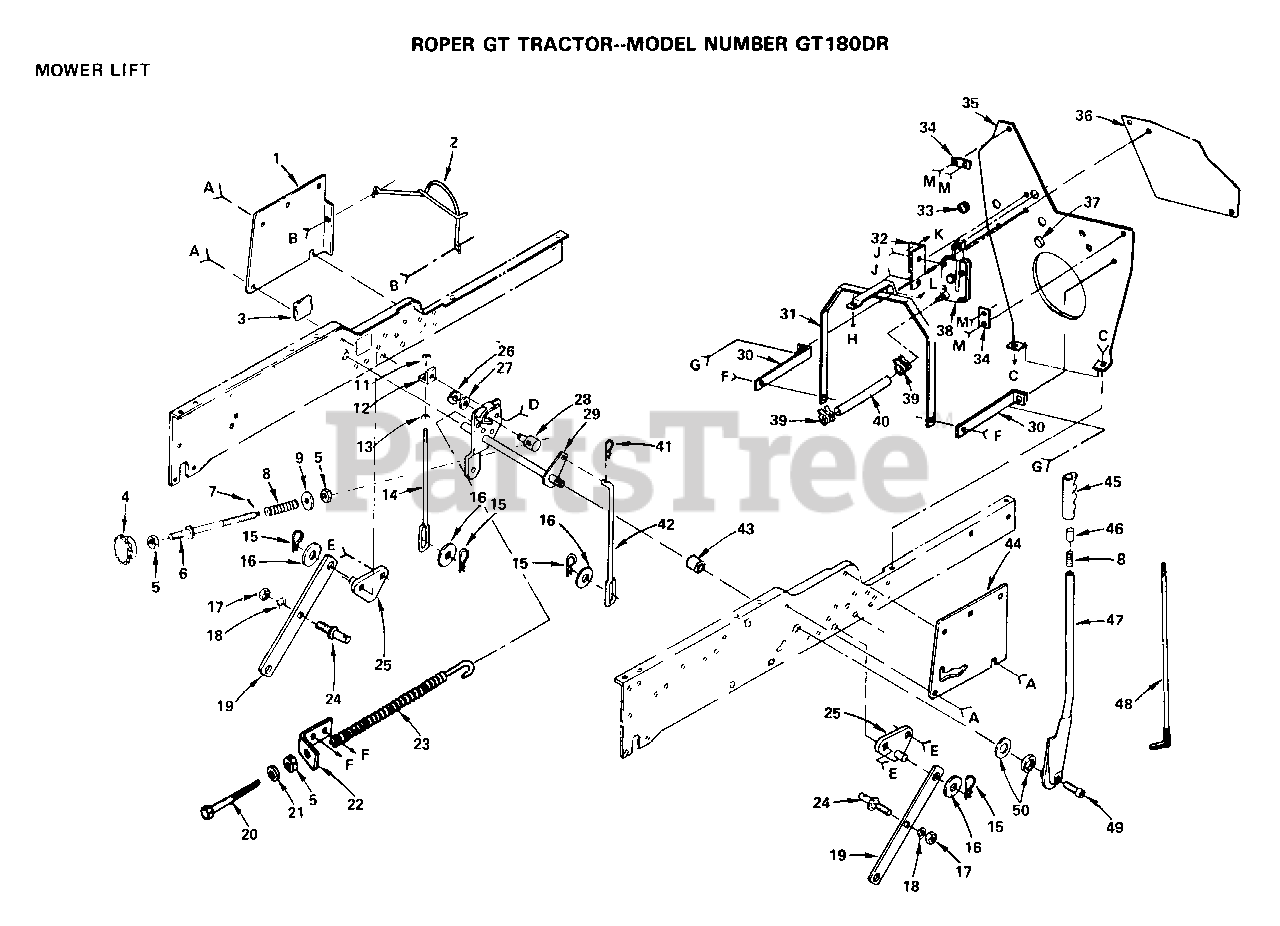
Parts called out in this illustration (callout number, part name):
2	ENGINE BELT GUARD
5	NUT
8	SPRING T
9	WASHER
11	NUT
12	BRACKET T
13	NUT.HEX.3/8-16UNC
14	LINK-LIFT MOW T
15	SPRING H
17	NUT
18	LOCKWASHER
19	SUSPENSION ARM GT
21	WASHER
24	PIVOT STUD GT
25	SUSP BRACKET T
26	KLIP RING
27	WASHER
28	TRUNION T
29	LIFT SHAFT GT
30	BRKT-SHIELD, HEAT, SIDE
33	SNAP BUSHING T
36	PANEL-SHIELD, HEAT
37	PLUG GT
42	LIFT LINK RH T
45	GRIP
49	SCREW LT
